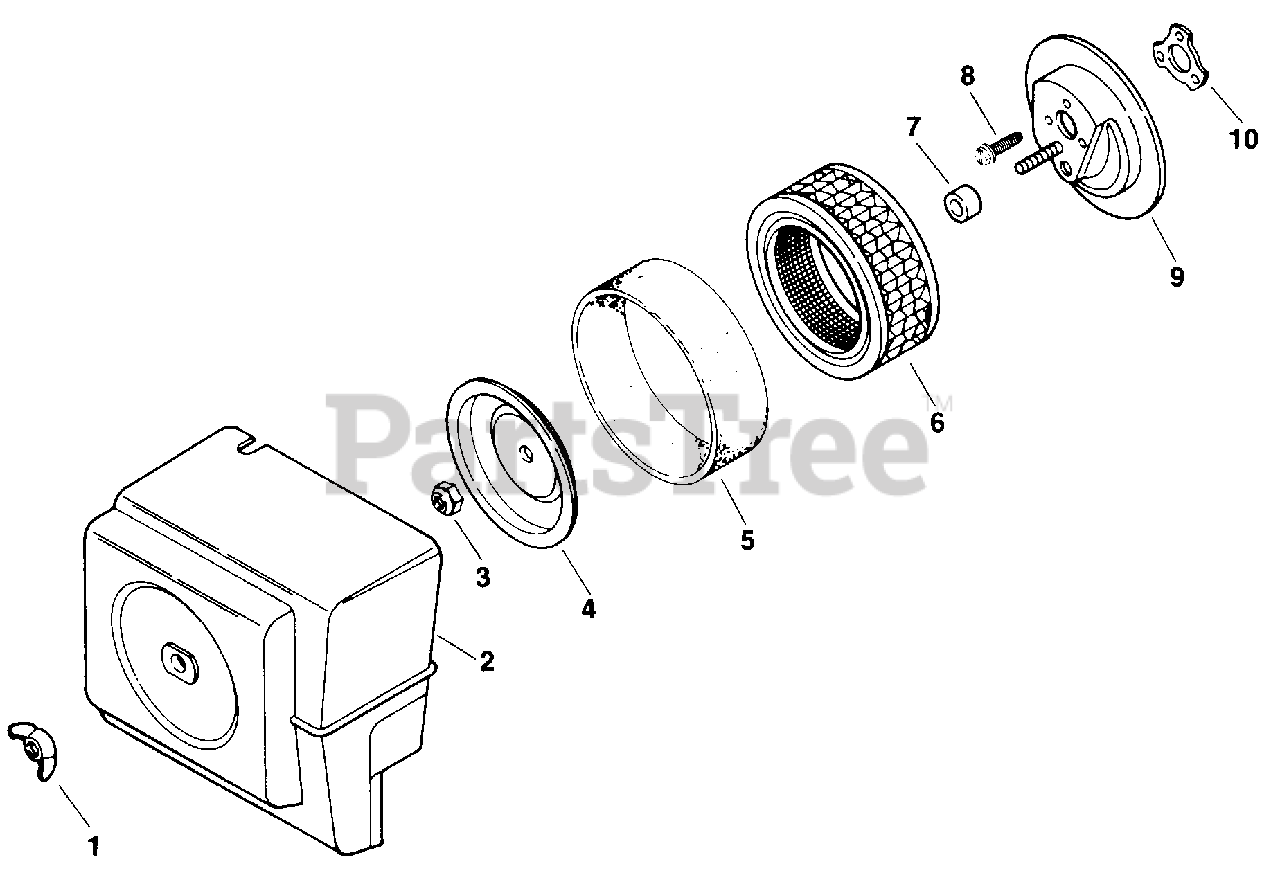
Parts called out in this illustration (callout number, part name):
1	Wing Nut 1/4-20
2	Cover, Air Cleaner
3	Nut, Jam 1/4-20
4	Cover, Air Cleaner Element
6	Element, Air Cleaner
8	Screw, R.H.M. 8-32 x 3/8
9	Base, Air Cleaner
10	Gasket, Air Cleaner
